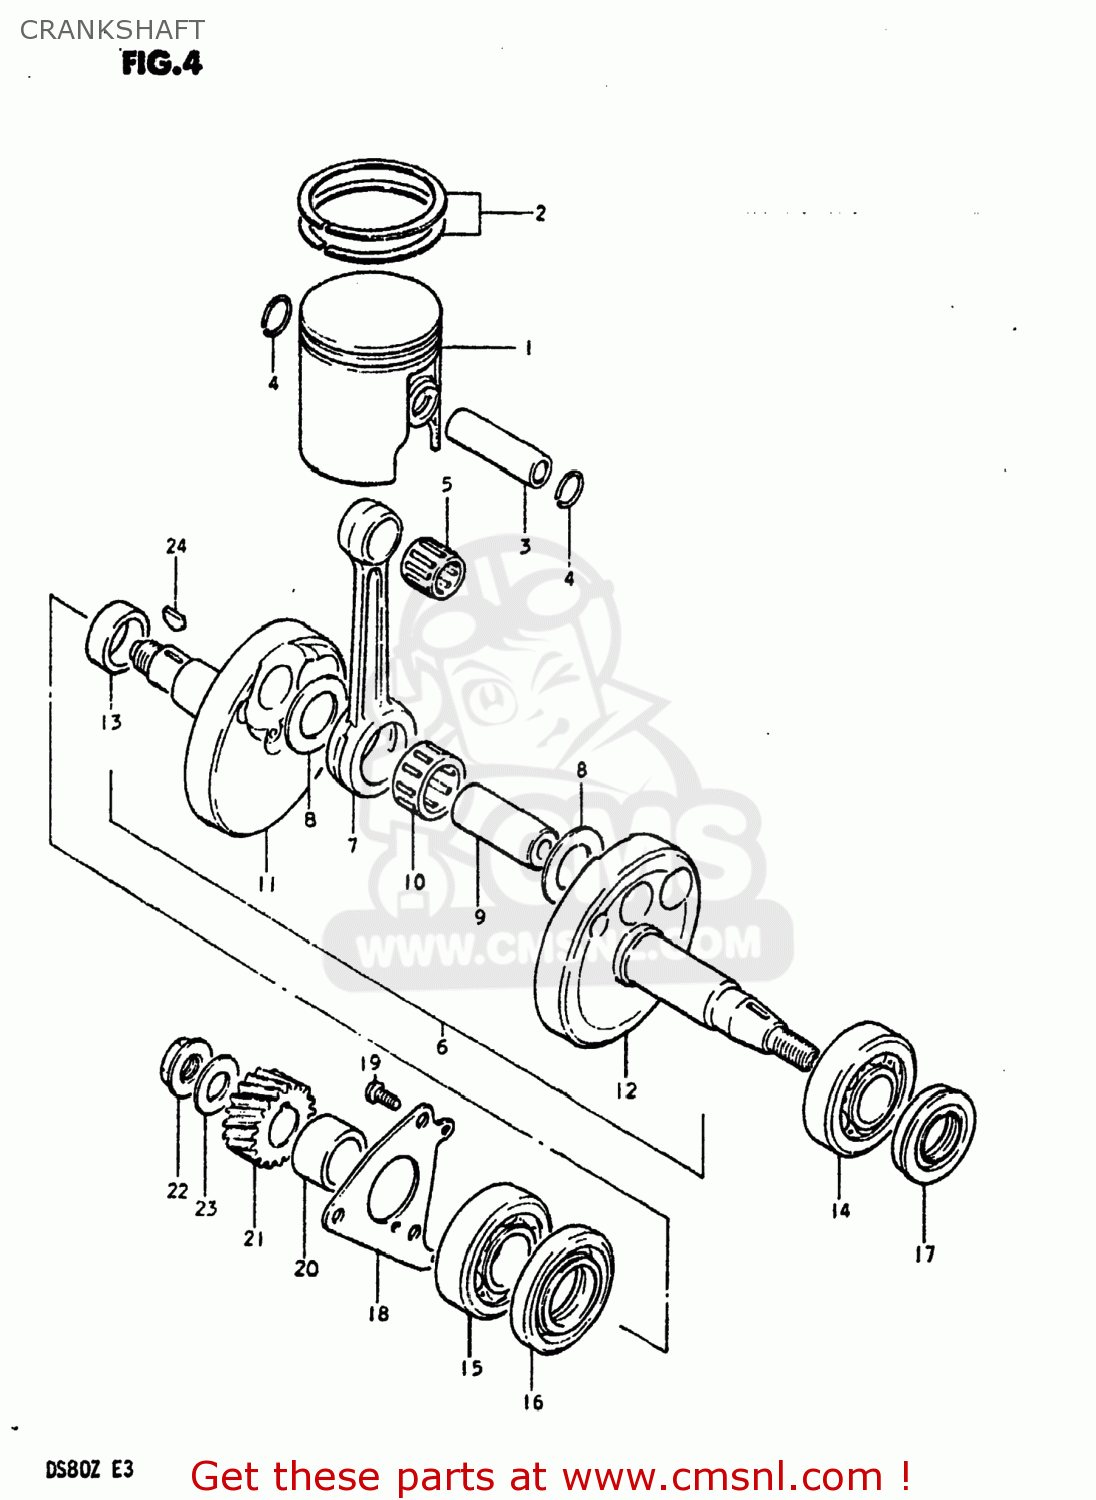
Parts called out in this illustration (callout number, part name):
1	PISTON
2	RING SET,PISTON
3	PIN,PISTON
4	RING,SNAP
5	BEARING
6	CRANKSHAFT ASSEMBLY
7	ROD,CONNECTING
8	WASHER
9	PIN,CRANK
10	BEARING
11	CRANKSHAFT,RIGHT
12	CRANKSHAFT,LEFT
13	SPACER(20X26X9)
14	BEARING
15	BEARING
16	OIL SEAL
17	SEAL,OIL(19.6X37X8)
18	RETAINER,CRANKSHAFT BEARING,R
19	SCREW 6X12
20	SPACER(20X26X14)
21	GEAR,PRIMARY DRIVE NO.19
22	NUT
23	WASHER
24	KEY
